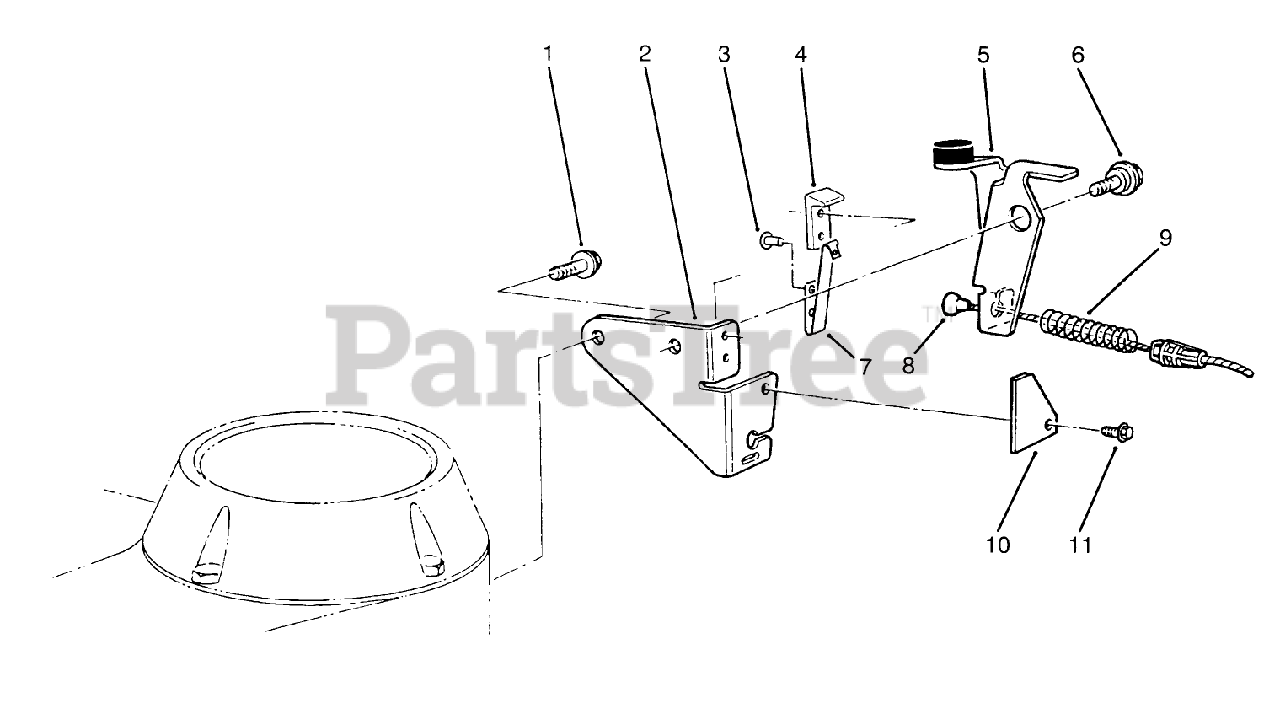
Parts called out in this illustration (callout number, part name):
1	SCREW-HWH
2	PLATE-BRAKE
3	RIVET-PLASTIC
4	STRAP-INSULATING
5	BRAKE PLATE ASM
6	SCREW-SHOULDER
7	STRAP-GROUND
8	BRAKE CABLE
9	SPRING-COMPRESSION
10	STOP-GROUND STRAP
11	SCREW-HWH
